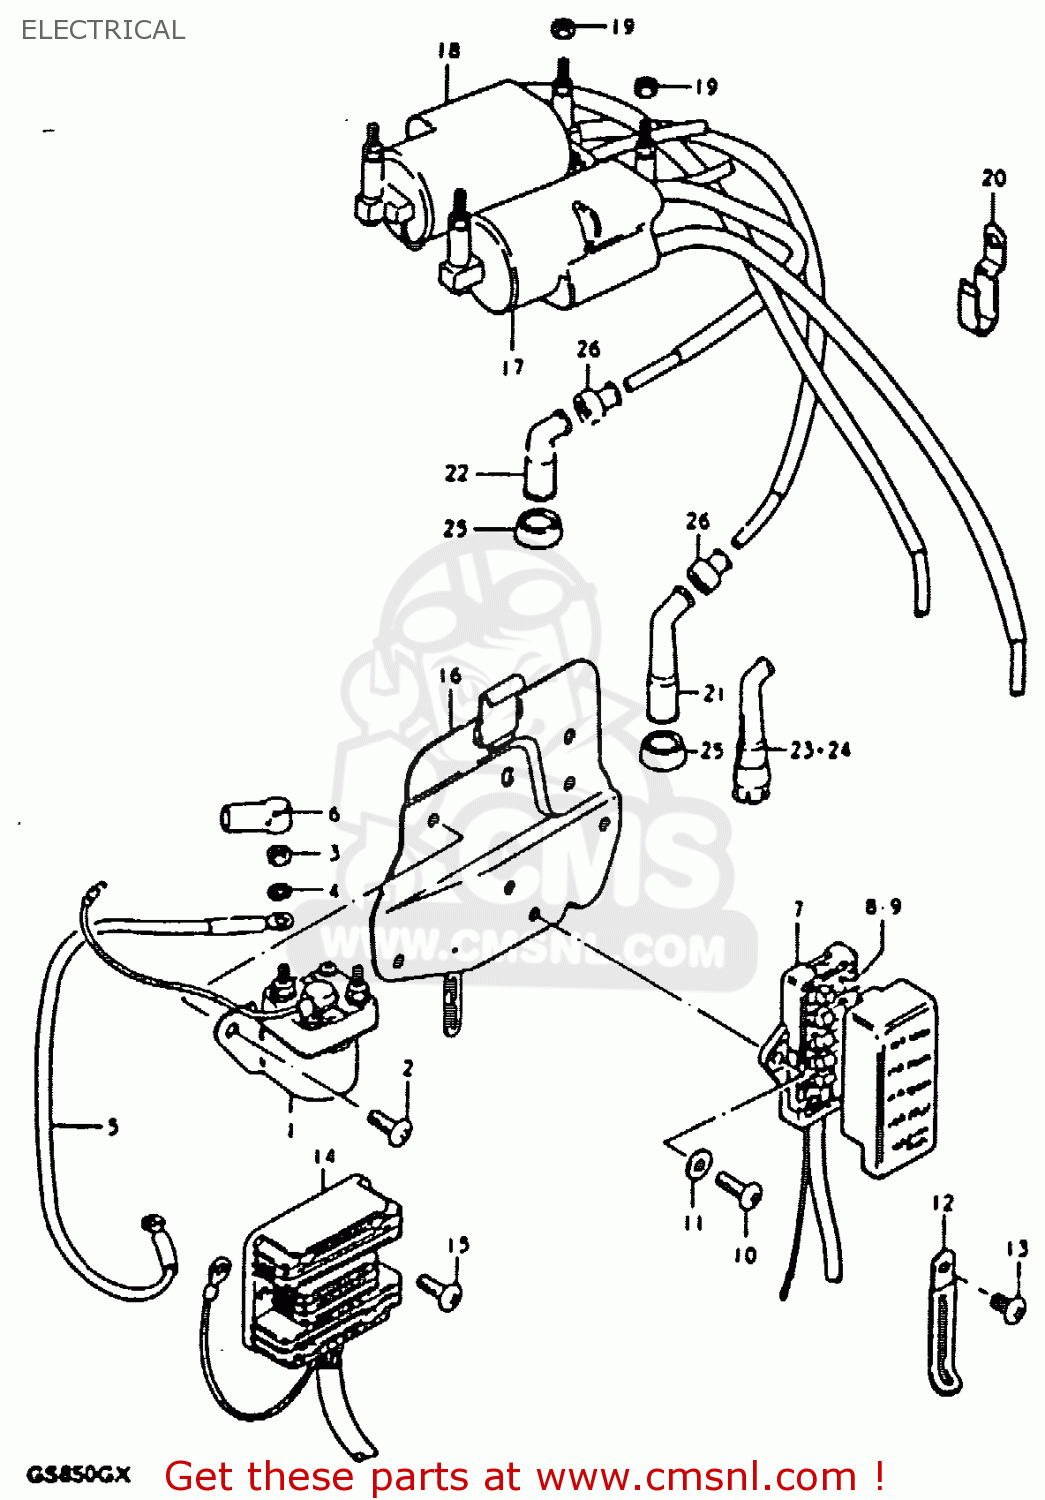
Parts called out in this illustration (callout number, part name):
1	RELAY ASSY,STARTING MOTOR
2	SCREW
3	NUT 6MM
4	LOCK WASHER
5	WIRE,STARTER MOTOR LEAD
6	CAP,STARTER RELAY
7	BOX ASSEMBLY,FUSE
8	FUSE(10A)
9	FUSE(15A)
10	SCREW 6X12
11	WASHER
12	CLAMP L:35
13	SCREW
14	RECTIFIER ASSEMBLY
15	SCREW 6X12
16	HOLDER COMP,ELECTRONIC PARTS
17	COIL ASSEMBLY,IGNITION
18	COIL ASSEMBLY,IGNITION
19	NUT
20	CLAMP
23	CAP,SPARK PLUG
24	CAP, SPARK PLUG (S)
25	SEAL,SPARK PLUG
26	SEAL,SPARK PLU
